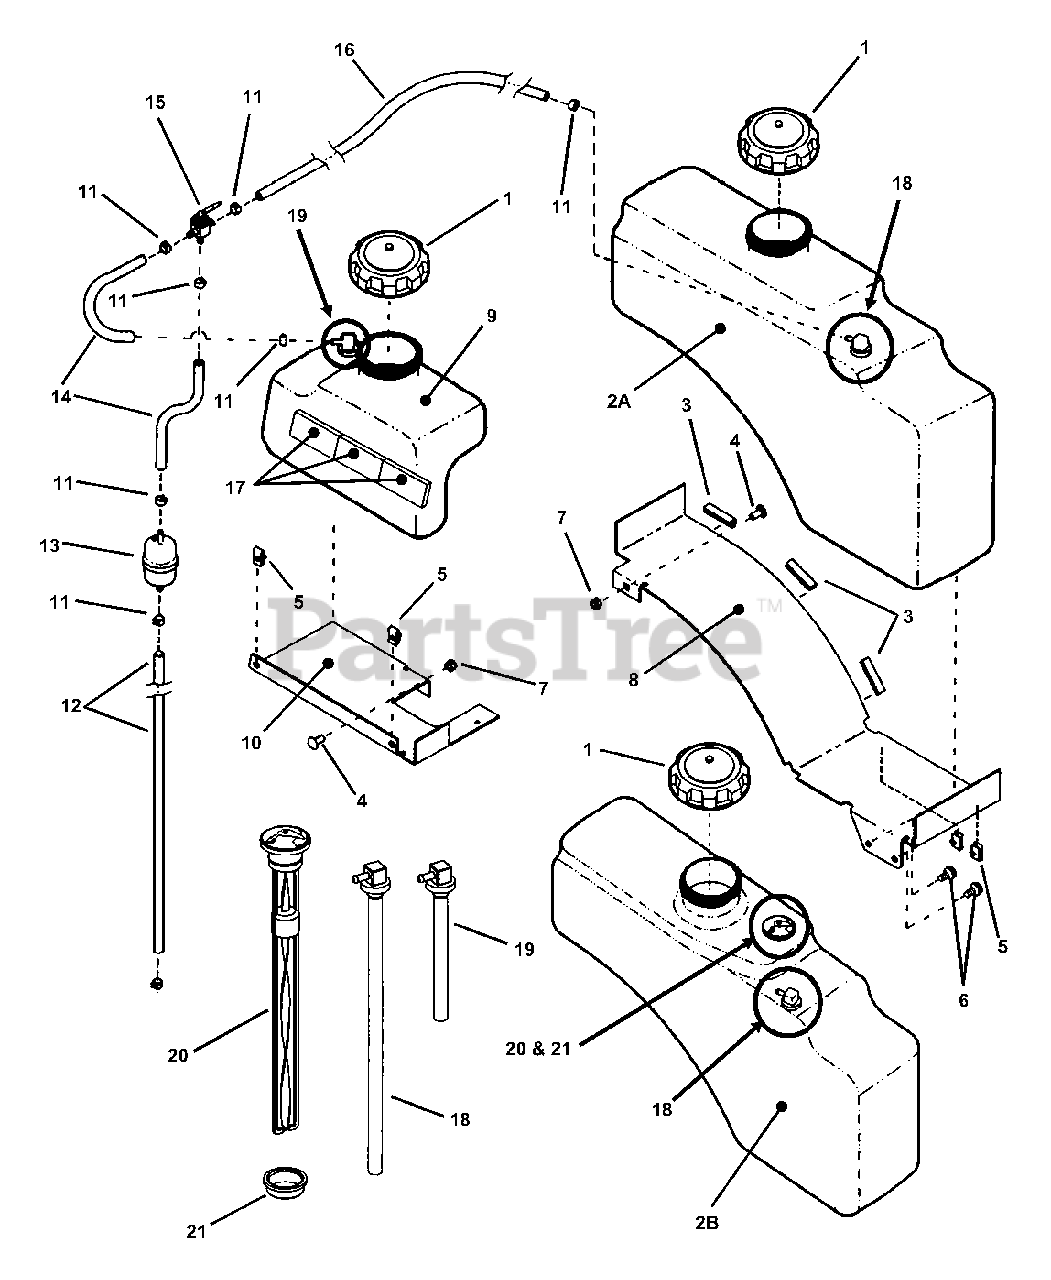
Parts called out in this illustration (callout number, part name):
1	CAP, 3-1/2" Fuel
2A	FUEL TANK, Main
2B	FUEL TANK, Main
3	TRIM, 2 Inch
4	BOLT, 5/16-18 x 3/4" Short Neck Carriage Grade 5
5	U-NUT, 1/4-20 Locking
6	SCREW, 5/16-18 x 5/8" Hex Washer Self Tapping
7	NUT, 5/16-18 HEX NYLON LOCK
8	BRACKET, Fuel Tank Support
9	FUEL TANK, Auxiliary
10	BRACKET, Mounting Auxiliary Fuel Tank
11	CLAMP, 7/16" Hose
12	HOSE, 1/4" I.D. x 10" Fuel
13	FILTER, 15 Micron Fuel
14	HOSE, 1/4" I.D. x 4" Fuel
15	VALVE, 3-Way Fuel
16	HOSE, 1/4" I.D. x 45" Fuel
18	ASSEMBLY, Fuel Pick-up (Main) (11.75" Long)
19	ASSEMBLY, Fuel Pick-up (Auxiliary) (5.25" Long)
20	FUEL GAUGE, Kelch
21	GROMMET, Fuel Tank Gauge
